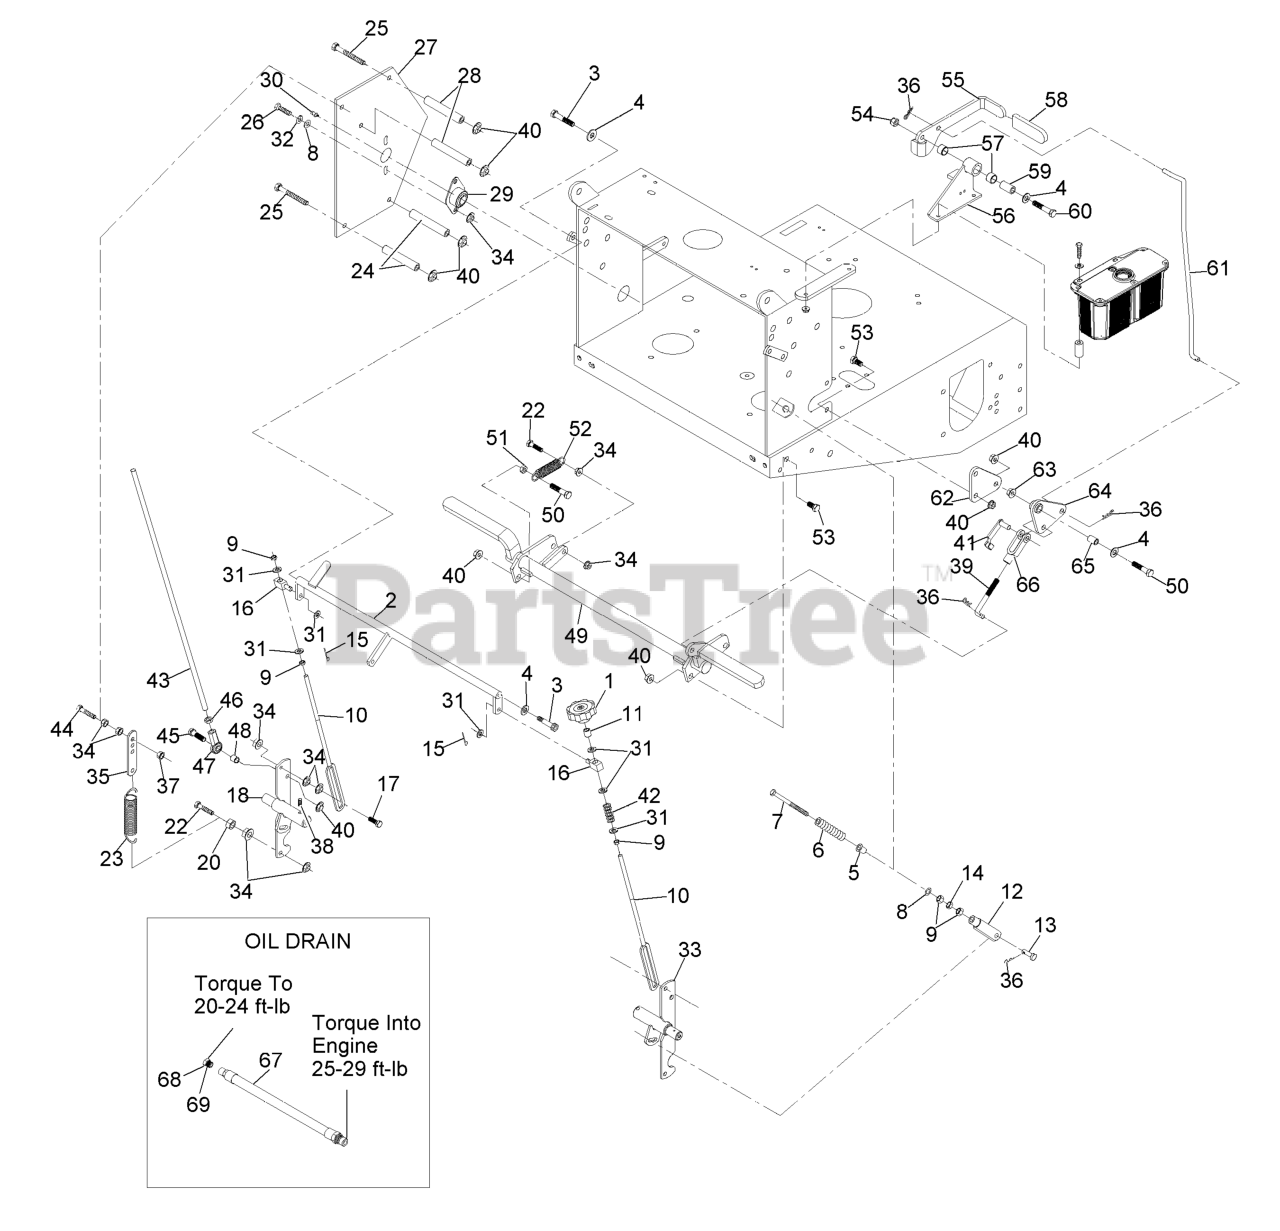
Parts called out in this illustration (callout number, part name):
1	KNOB-TRACKING
2	CRANK-CONTROL, SPEED
3	SCREW-HSH
4	WASHER-FLAT
5	BUSHING-FLANGED
6	SPRING,COMPRESSION (NEUT)
7	BOLT-RETURN, NEUTRAL
8	WASHER-FLAT
9	NUT-HEX
10	LINK-CONTROL, SPEED
12	YOKE-ADJUSTABLE
13	PIN-CLEVIS
14	NUT-JAM
15	PIN-COTTER
17	SCREW-HH
18	SHAFT-CONTROL, LH
20	NUT-JAM
22	SCREW-HH, SPECIAL
23	SPRING-EXTENSION
24	SPACER-SHIELD
25	SCREW-HH
26	SCREW-HH
27	SHIELD-CONTROL
28	SPACER-SHIELD
29	BEARING-FLANGE, SIDE
30	FITTING-GREASE
31	WASHER-PLAIN
32	WASHER-LOCK
33	SHAFT-CONTROL, RH
35	TAB-SPRING, EXTENSION
36	PIN-COTTER
37	NUT-LOCK, NI
38	SCREW-SET
39	LINKAGE-LOWER
40	NUT-HHF, WHIZ
41	PIN-SPRING, CLEVIS
42	SPRING-COMPRESSION
43	LINKAGE,DRIVE (PLT)
44	BOLT-TAP, HH
45	SCREW-HH
46	NUT-HEX JAM, LH
47	JOINT-BALL END, LH
48	SPACER-TUBE, PUMP LINK
50	SCREW-HH
51	NUT-JAM
52	SPRING-IDLER
53	SCREW-HH
54	NUT-LOCK, NI
55	LEVER,PARK BRK W/DECAL
56	BRACKET ASM
57	SLEEVE-BUSHING
58	GRIP-LEVER
59	BUSHING-PIVOT
60	SCREW-HH
61	LINKAGE-UPPER
62	BELLCRANK
63	SCREW-HH
64	BELLCRANK ASM
65	BUSHING-PLASTIC
66	YOKE-LINKAGE, BRAKE
67	ASM, ENGINE OIL DRAIN HOS
68	PLUG-HH
69	O-RING
